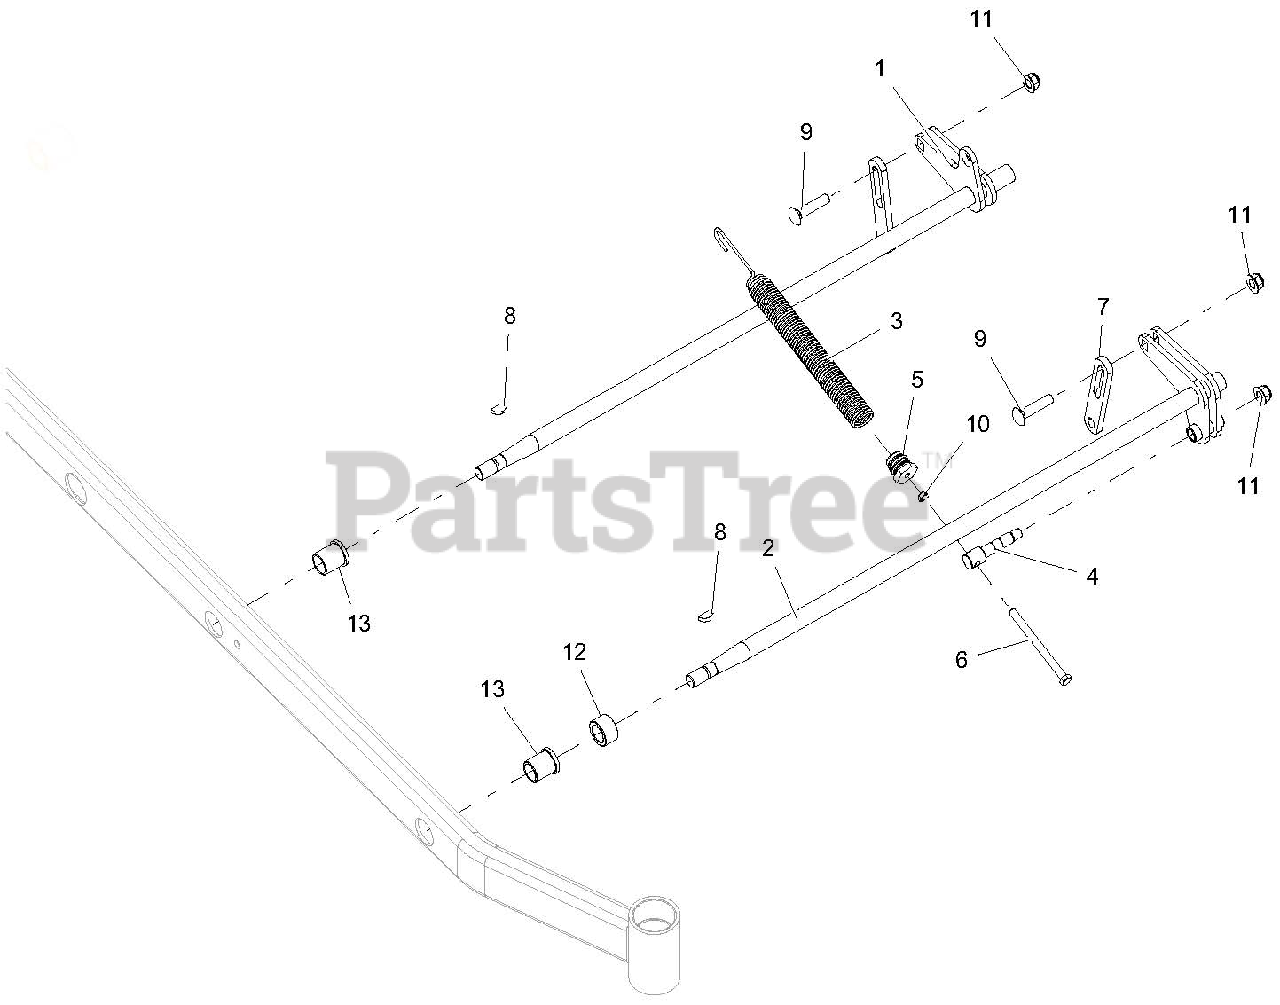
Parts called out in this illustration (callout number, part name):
1	WLDMT, REAR LH DECK LIFT ARM-BLACK
2	WLDMT, FRONT LH DECK LIFT ARM-BLACK
3	SPRG, DECK LIFT
4	TRUNION, SPRG
5	PLUG, SPRG
6	BLT-HEX .38-16X5.00 GR5 YWZC
7	LINK, DECK LIFT - LONG
8	KEY, WDRF .25 X 1.00 HRD #15
9	BLT-RDHDSQNK .50-13X2.25 G5Y
10	NUT, JAM .375-16 YWZC
11	NUT-LK-NYL-FLG .50-13 YWZC
12	SPACER, 1.500 X 1.000 X .880
13	BSHG-FLG 1.00X1.25X1.5X1.5
